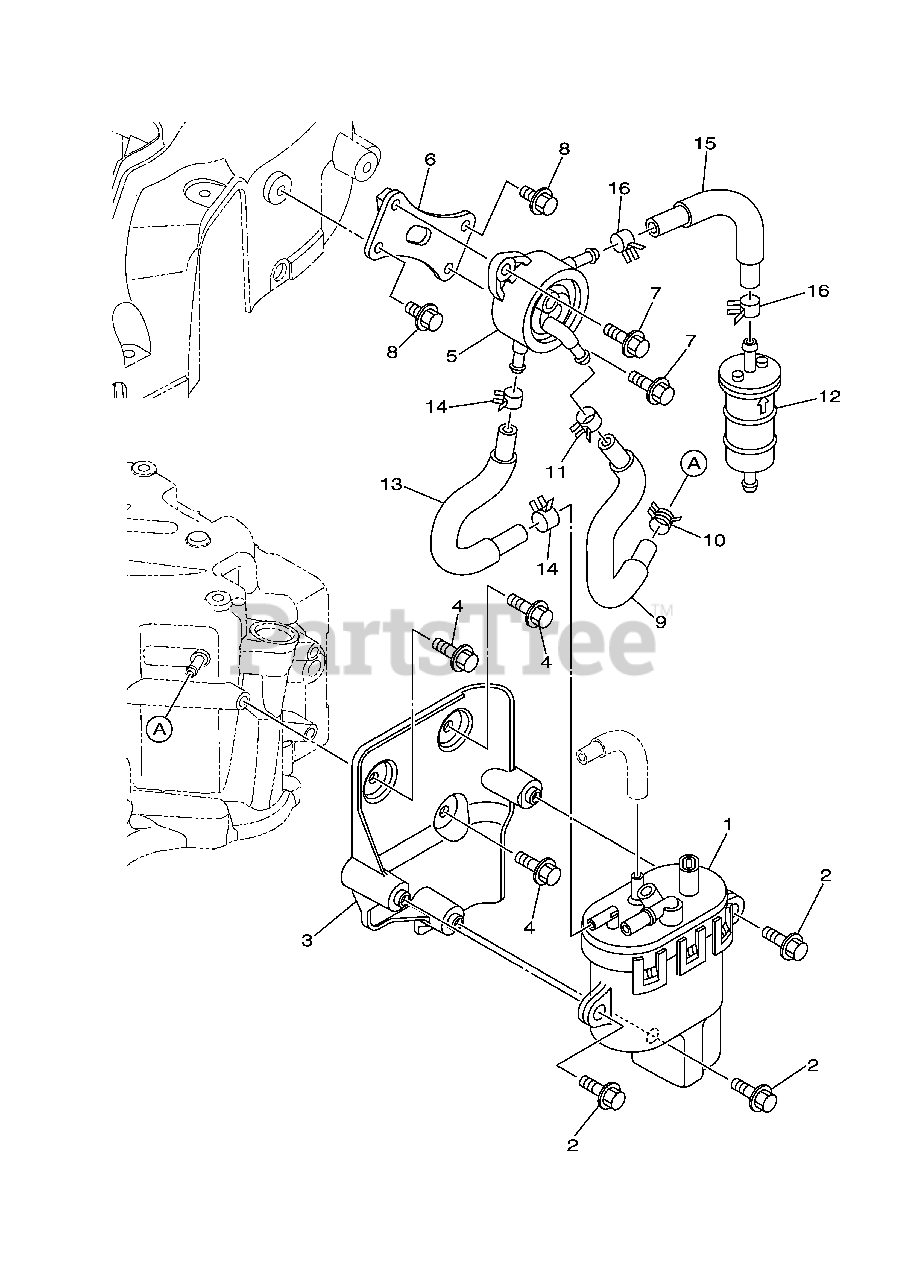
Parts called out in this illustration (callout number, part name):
1	FUEL PUMP COMP.
2	BOLT, FLANGE
3	BRACKET, FUEL PUMP 1
4	BOLT, FLANGE
5	FUEL PUMP ASSY
6	BRACKET, FUEL PUMP 2
7	BOLT, FLANGE
8	BOLT, FLANGE
12	FILTER-FUEL
13	PIPE, FUEL 1
15	PIPE, FUEL 2
